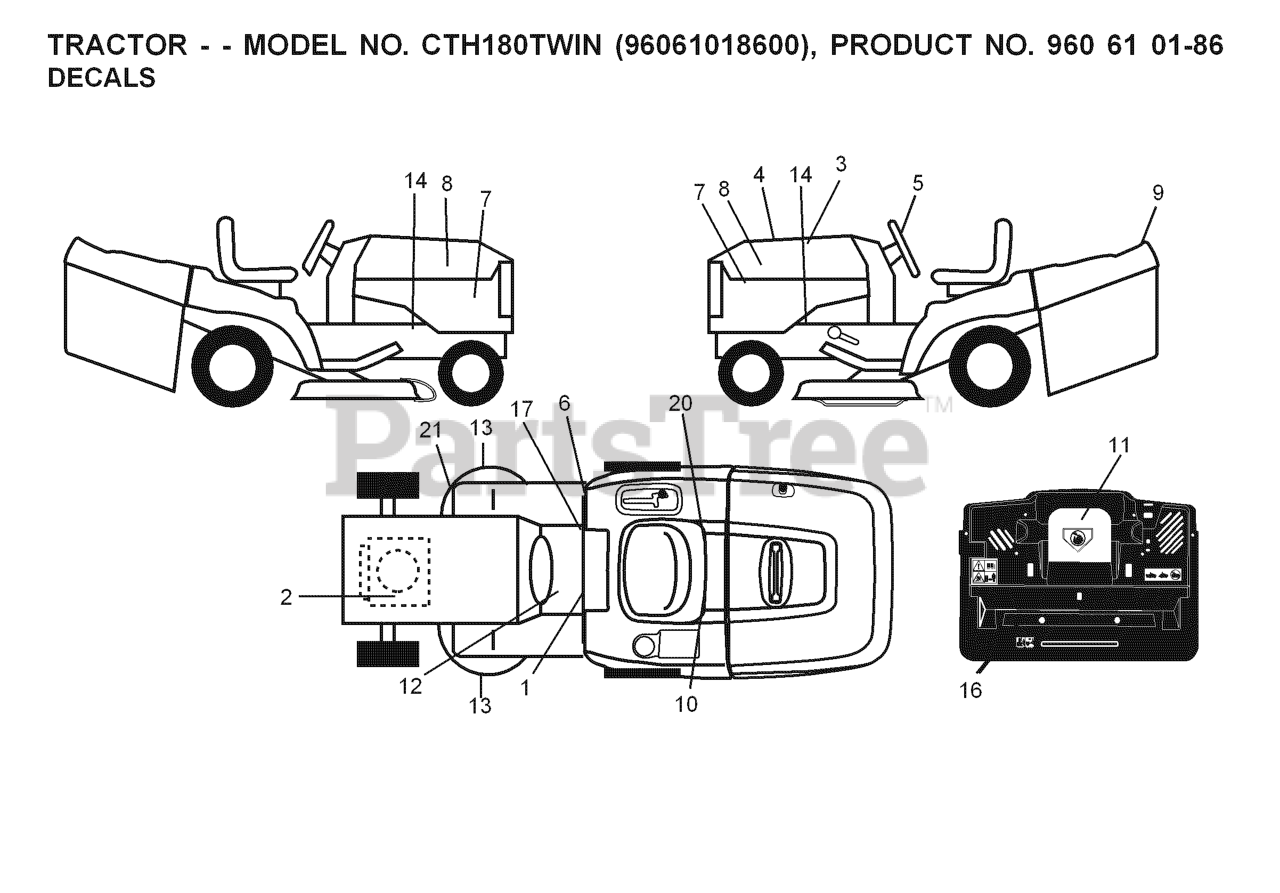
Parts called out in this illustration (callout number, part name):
1	LABEL
2	DECAL
3	DECAL.HOOD.TOP.INSERT.
5	DECAL.WHEEL.STRG.LGN.H
6	Decal, Fender 100 DB/CE
8	DECAL.HOOD.NAMELOGO.HUSQ
9	Decal, Fender 100 DB/CE
10	DECAL BTRY SYMBOLS
11	DECAL.INTERNATIONL.CUTFINGER
12	DECAL
16	DECAL
17	DECAL PARK BRAKE
20	DECAL.BYPASS.FENDER.CRD.LT.YT
